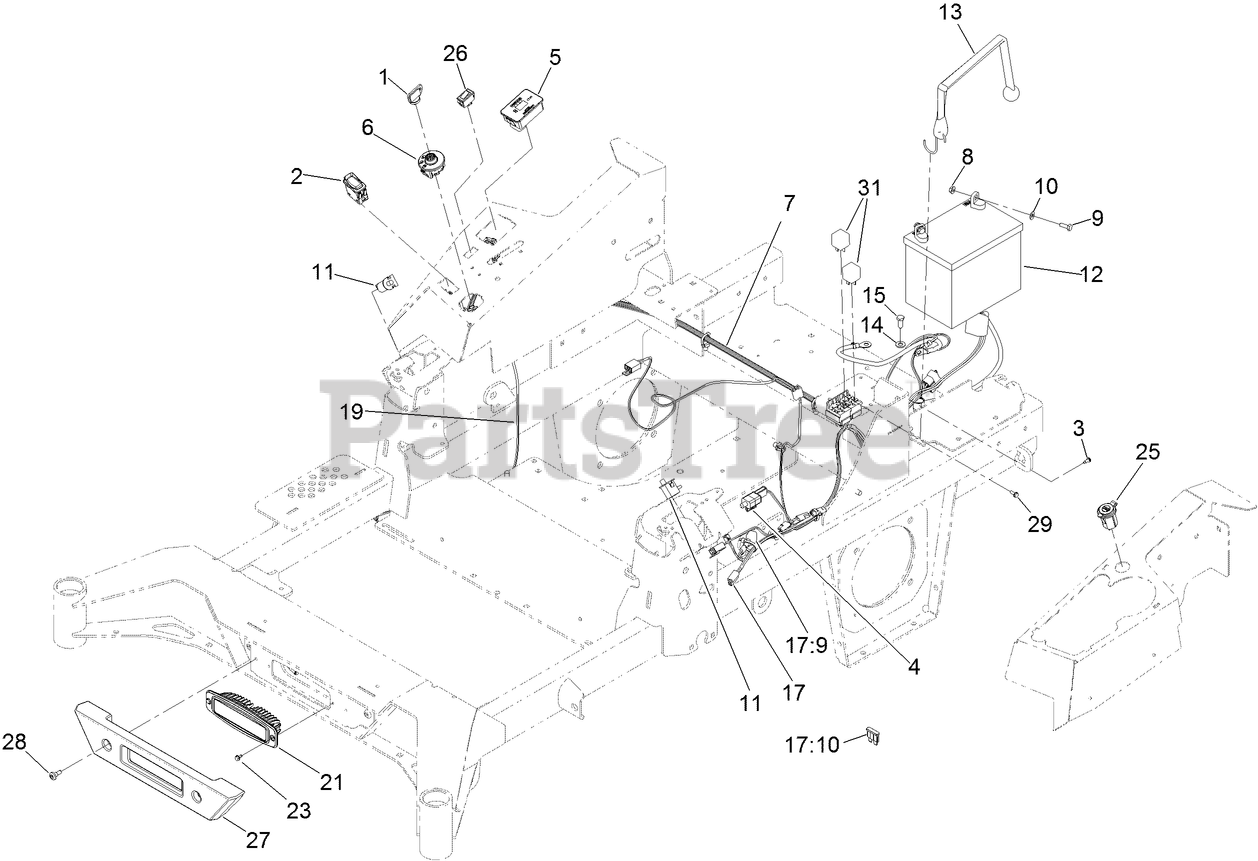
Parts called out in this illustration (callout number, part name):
1	KEYS-IGNITION (SPARE PAIR)
1	KEY-IGNITION
2	SWITCH-ROCKER, ON-NONE-ON
3	SCREW-FORMING, THREAD
4	SWITCH
5	MODULE ASM
6	SWITCH-IGNITION
7	HARNESS-WIRE
8	NUT-HF
9	SCREW-HH
10	WASHER-FLAT
11	SWITCH-BAIL
12	BATTERY-DRY
13	STRAP-BUNGEE
14	WASHER-PLAIN
15	SCREW-HH
17	HARNESS-WIRE, DECK LIFT
17:10	FUSE-BLADE, 20 AMP
19	HARNESS-WIRE, LIGHT KIT
21	MOUNT-FLUSH, LIGHT
23	SCREW-HWH
25	PORT-POWER, USB
26	SWITCH-ROCKER
27	BUMPER-FRONT
28	SCREW-SHOULDER
29	SCREW-TAPTITE
